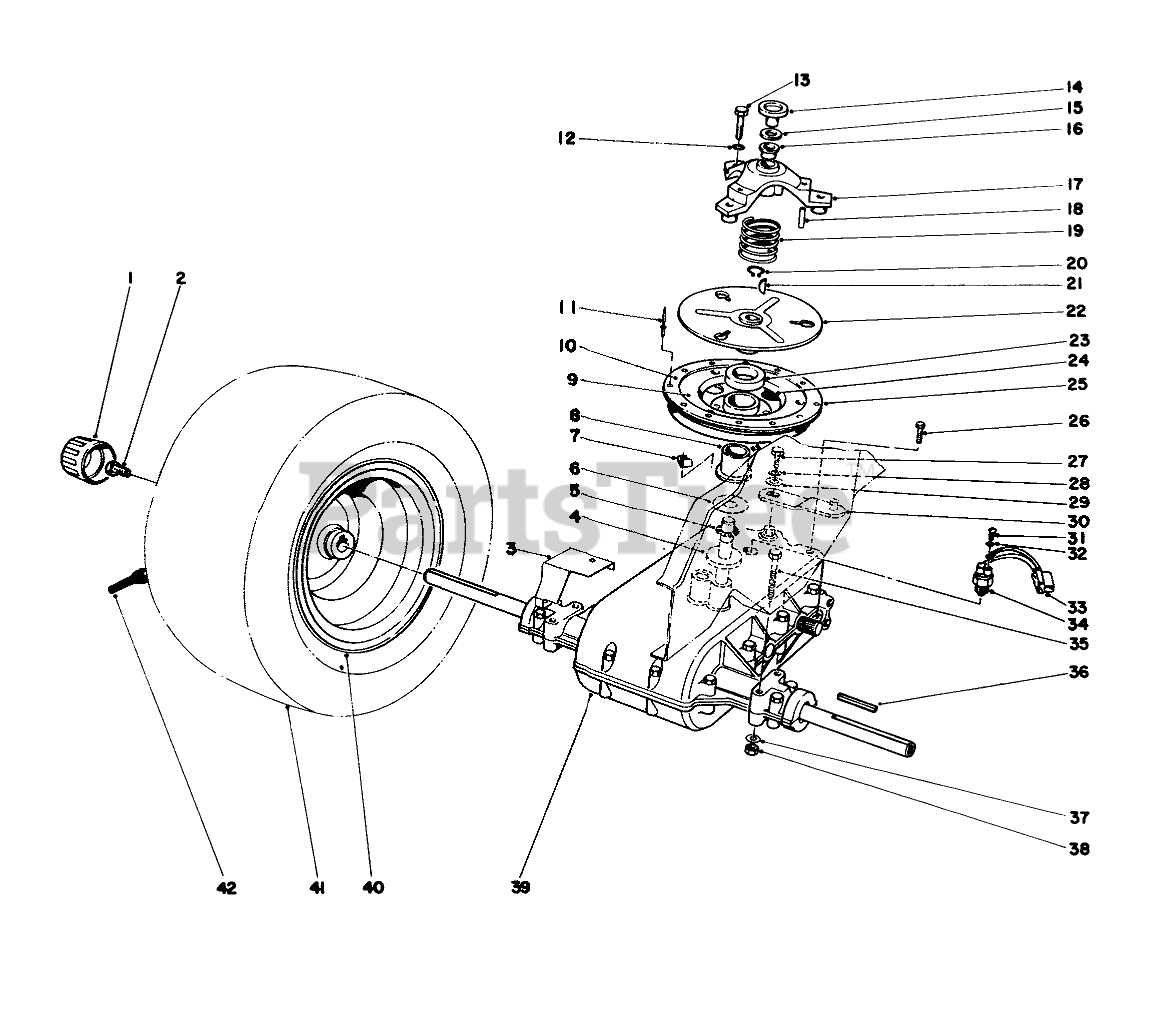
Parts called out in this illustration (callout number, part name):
1	Cap-Hub
2	CAPSCREW 3/8 16 3/4
3	GRASS SHIELD B
4	SPACER
5	NEEDLE BRG
6	THRUST WASHER
7	Clamp (Incl. with Main Wire Harness)
9	CLUTCH PAD
10	RETAINER RING R
11	RIVET
12	WASHER-LOCK
13	SCREW-HH
14	CLUTCH CAP
15	THRUST RACE
16	BUSHING-FLANGE
17	Clutch Cover Assembly (Incl. Ref. #16 & 18)
18	NEEDLE BRG
19	COMPRESSION SPRING
20	RING-SNAP, EXTERNAL
21	KEY-WOODRUFF
22	Clutch Plate
23	WASHER FELT
25	Sheave Assembly (Incl. Ref. #8-11)
26	SCREW-HWHTF
27	SCREW-HH
28	WASHER-LOCK
29	WASHER-FLAT
30	SHIFT LEVER WA B
31	SCREW
32	WASHER-LOCK/INT
33	WIRE HARNESS
34	NEUTRAL SWITCH
35	SCREW-HH
37	WASHER-PLAIN
38	NUT-LOCK, NI
39	TRANSAXLE
40	REAR WHEEL ASSEMBLY
41	REAR TIRE
42	STEM-VALVE
